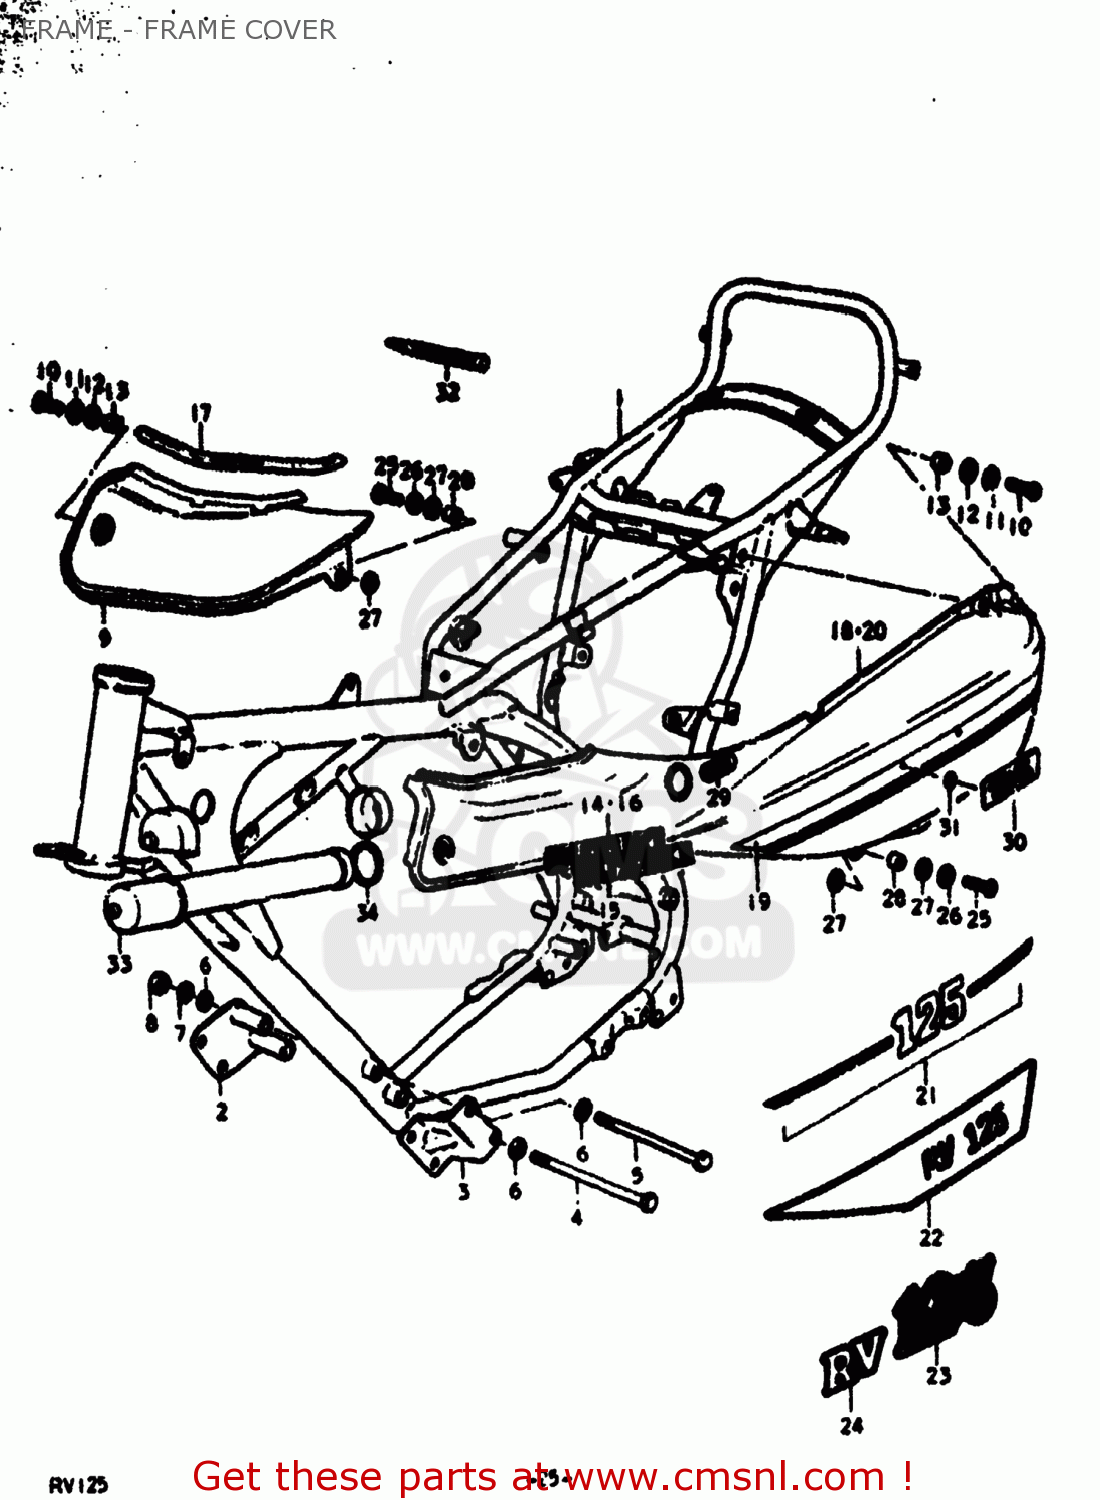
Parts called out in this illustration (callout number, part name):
1	FRAME
2	PLATE,ENGINE MOUNTING
4	HEXAGON BOLT 8X80
5	BOLT,8X75
6	WASHER
7	LOCK WASHER
8	NUT
9	COVER,FRAME,RIGHT
10	SCREW
11	WASHER
12	CUSHION
13	SPACER(8.2X10X8)
14	EMBLEM,SUB FUEL TANK
15	EMBLEM
16	EMBLEM
18	COVER,FRAME,LEFT
19	TAPE,FRAME COVER
20	COVER,FRAME,LEFT
21	TAPE,FRAME COVER
22	TAPE,FRAME COVER
23	EMBLEM,FRAME COVER,LEFT
24	EMBLEM,RV
25	SCREW
26	WASHER
27	CUSHION
28	SPACER(8.2X10X8)
29	EMBLEM,CCIS
30	EMBLEM,FRAME COVER
31	NUT
33	INFLATOR, AIR
34	CUSHION
